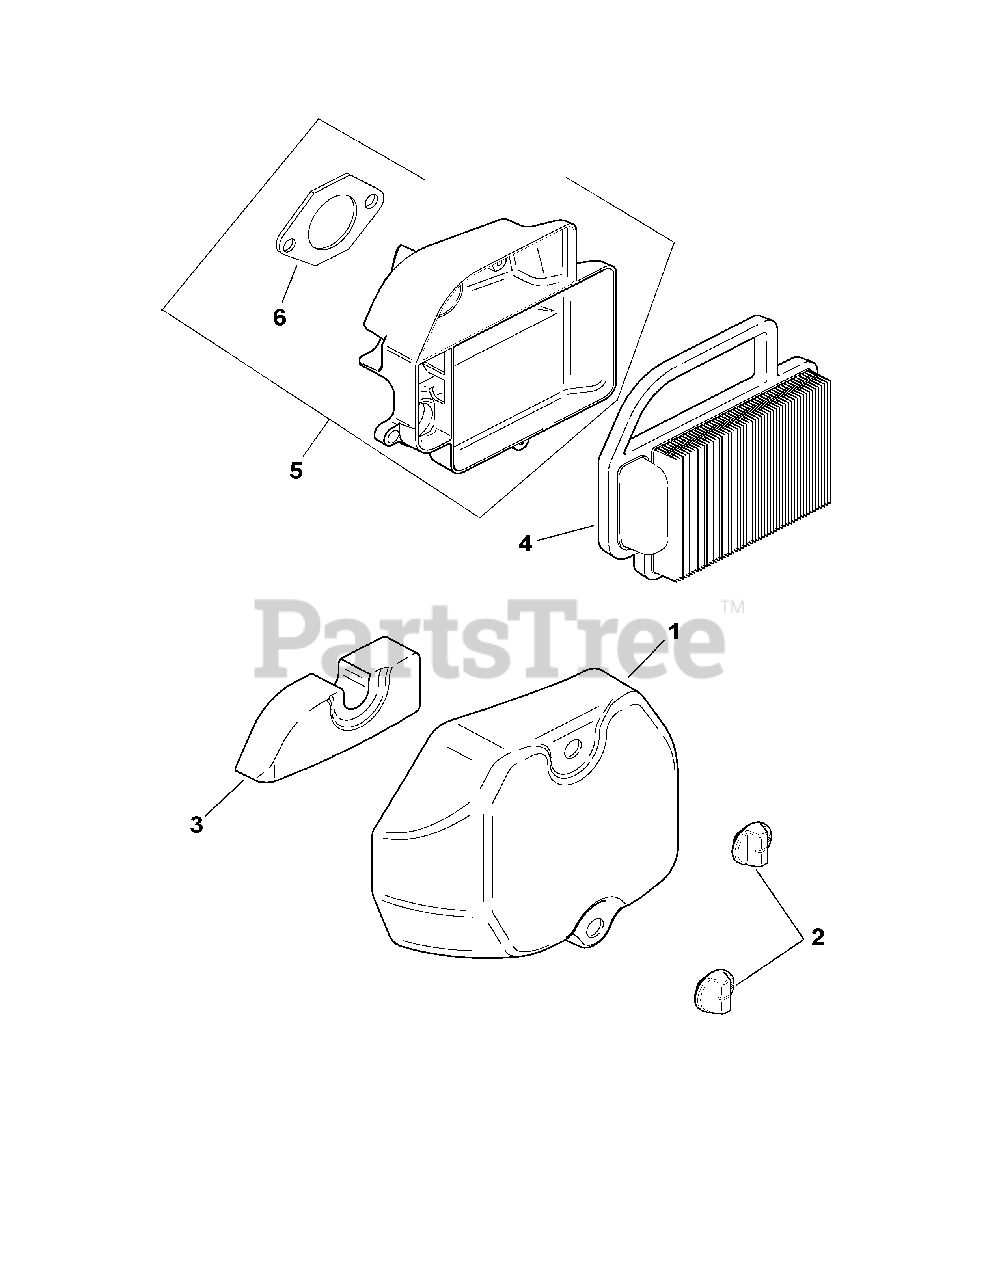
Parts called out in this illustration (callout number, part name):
1	Air Cleaner Cover
3	Precleaner Element
4	Air Cleaner Element
5	Air Cleaner Base Kit
6	Air Cleaner Base Gasket
